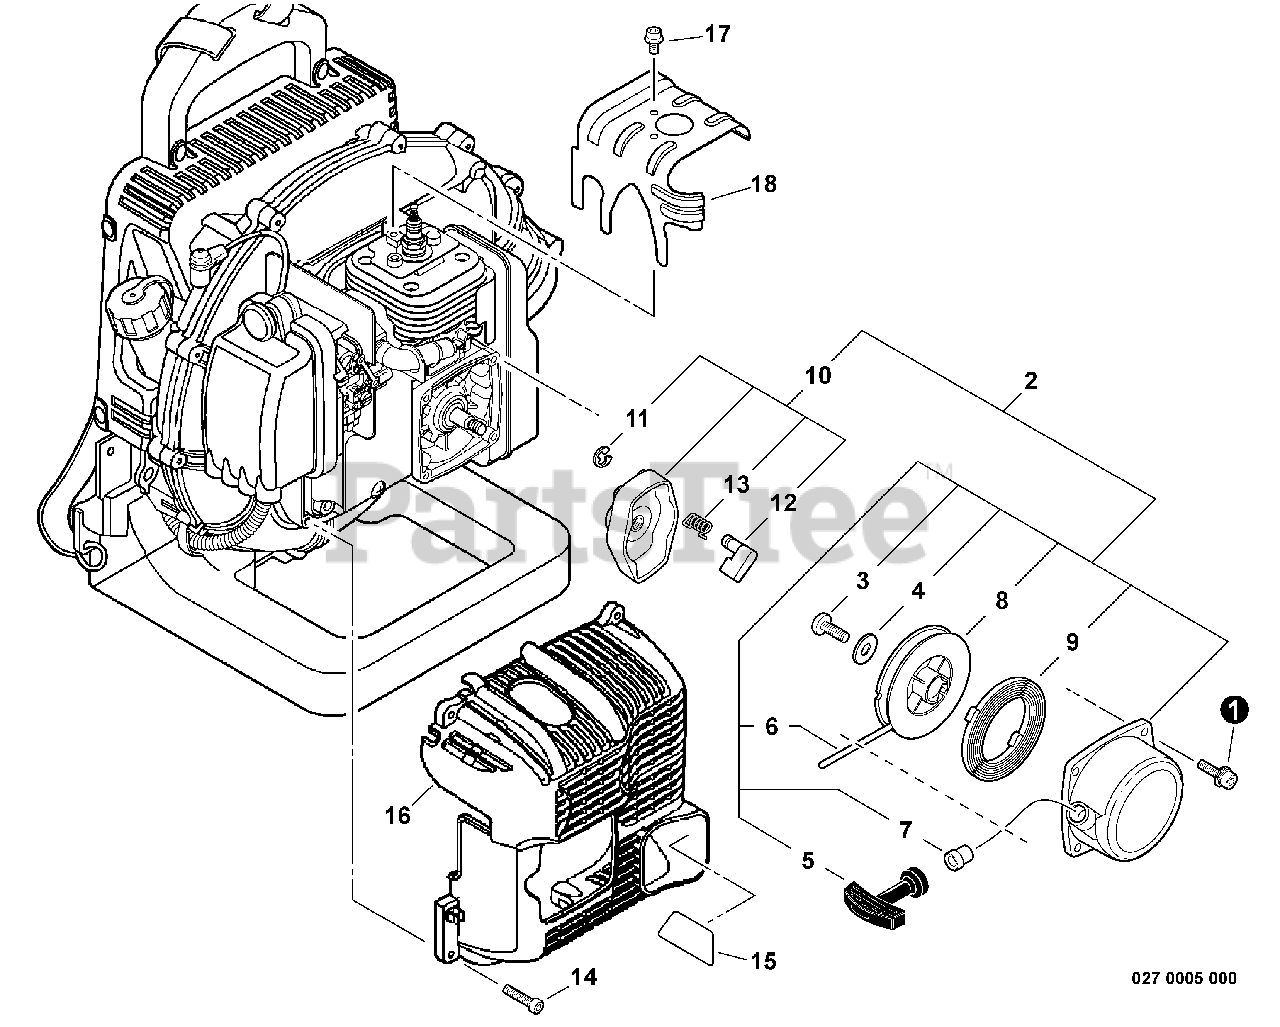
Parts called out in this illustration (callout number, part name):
1	SCREW - 5X18
2	STARTER KIT
5	GRIP, STARTER
6	ROPE, STARTER - 4X1110
7	GUIDE, ROPE
8	REEL, ROPE
9	SPRING, REWIND
10	STARTER PAWL ASSY
11	RING, RETAINING - 4
12	PAWL, STARTER
13	SPRING, RETURN
14	SCREW - 5X20 -- TAPPING
15	DEFLECTOR, HEAT
16	COVER, ENGINE
17	SCREW - 5X8
18	SHIELD, CYLINDER
